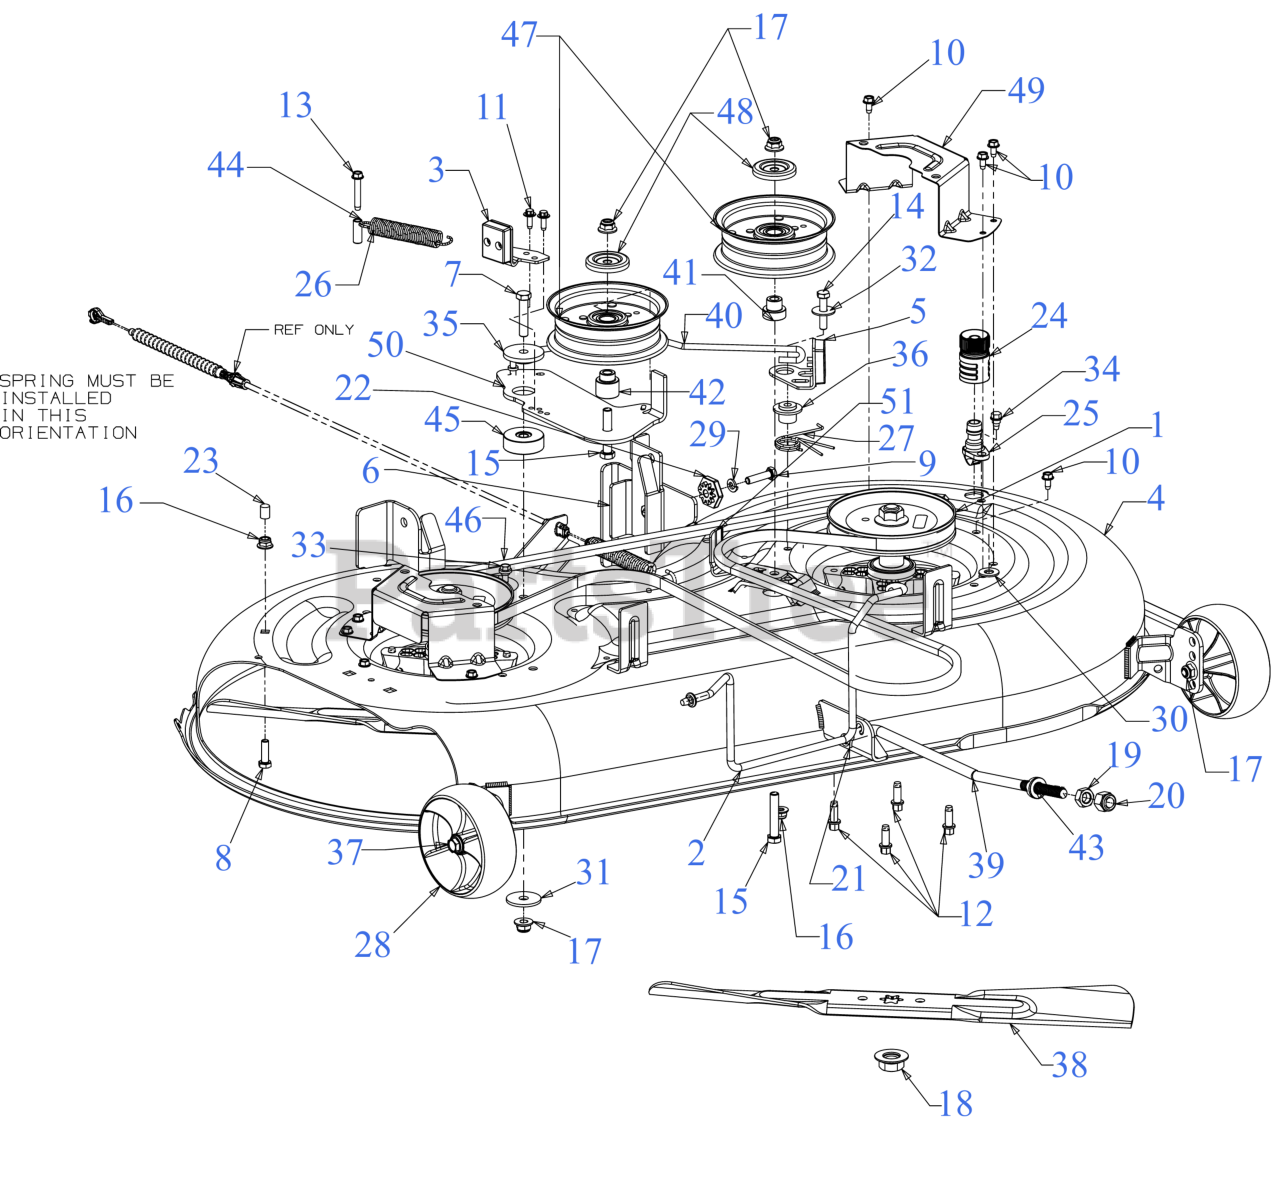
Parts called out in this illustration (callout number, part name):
1	SPINDLE ASSEMBLY 5.4"
1	Troy-Bilt 42" SPINDLE ASSEMBLY (06991)
2	BELT KEEPER ROD
3	DECK BRAKE ASSEMBLY (RH)
5	DECK BRAKE PAD
6	DECK HANGER BRACKET (LH)
7	HEX SCREW 3/8-16 x 1.75 GR5
8	SCREW 5/16-18 x 1.0 GR5
9	SCREW 5/16-18 x 1.25 GR5
10	SCREW 1/4-20 X.500
11	SCREW M6-1 x .625
12	SCREW 5/16-18 x .875
13	SCREW 1/4-20 x 1.50"
14	SCREW 5/16-18 x 1.5 LG
15	SCREW 3/8-16 x 2.0 GR 8
16	FLANGE LOCK NUT 5/16-18
18	FLANGE NUT 5/8-18
18	HEX NUT
20	HEX LOCK NUT NYLON
21	PIN:COTTER
22	DECK ADJUSTMENT GEAR
24	WATER NOZZLE ADAPTER
25	DECK WASH NOZZLE
26	EXTENSION SPRING
27	TORSION SPRING
28	DECK WHEEL (5.0 DIA x 1.875)
28	Cub Cadet 5" DECK WHEEL SET (06305A) (W/BOLT)
29	LOCK WASHER 5/16
30	FLAT WASHER
31	FLAT WASHER .406X1.500X.105
31	FLAT WASHER .390x1.500x.134
32	FLAT WASHER 344X1.00
33	SHOULDER SCREW
34	SHOULDER SCREW 1/4-20X.50 19"PSH
35	SHOULDER SPACER
36	DOUBLE SHOULDER SPACER .750 x .135
37	SHOULDER BOLT (.50 X 2.0 x 3/8 -16)
38	21.23" BLADE (2N1)
38	Cub Cadet 42" BLADE SET
38	Genuine Factory Parts 42" BLADE SET(2N1)
38	Troy-Bilt 42" BLADE SET(2N1)
38	21.23" BLADE (2N1) (XTREME)
38	Cub Cadet BLADE SET (XTREME)
38	BLD:XTREME SET MTD
38	42" 6 PT STAR LOW LIFT/SAND BLADE
39	DECK FRONT LIFT ROD
40	DECK BRAKE ROD
41	SHOULDER SPACER
42	SHOULDER SPACER
43	DECK LIFT PIVOT CUP
45	SPACER .385ID x 1.75OD x .585THK
46	V-BELT A SEC x 96.5
46	Genuine Factory Parts 42" DECK DRIVE BELT
46	Troy-Bilt 42" DECK DRIVE BELT (04060B)
47	IDLER PULLEY 4.50" DIA
48	IDLER PULLEY CAP
50	DECK IDLER BRACKET
